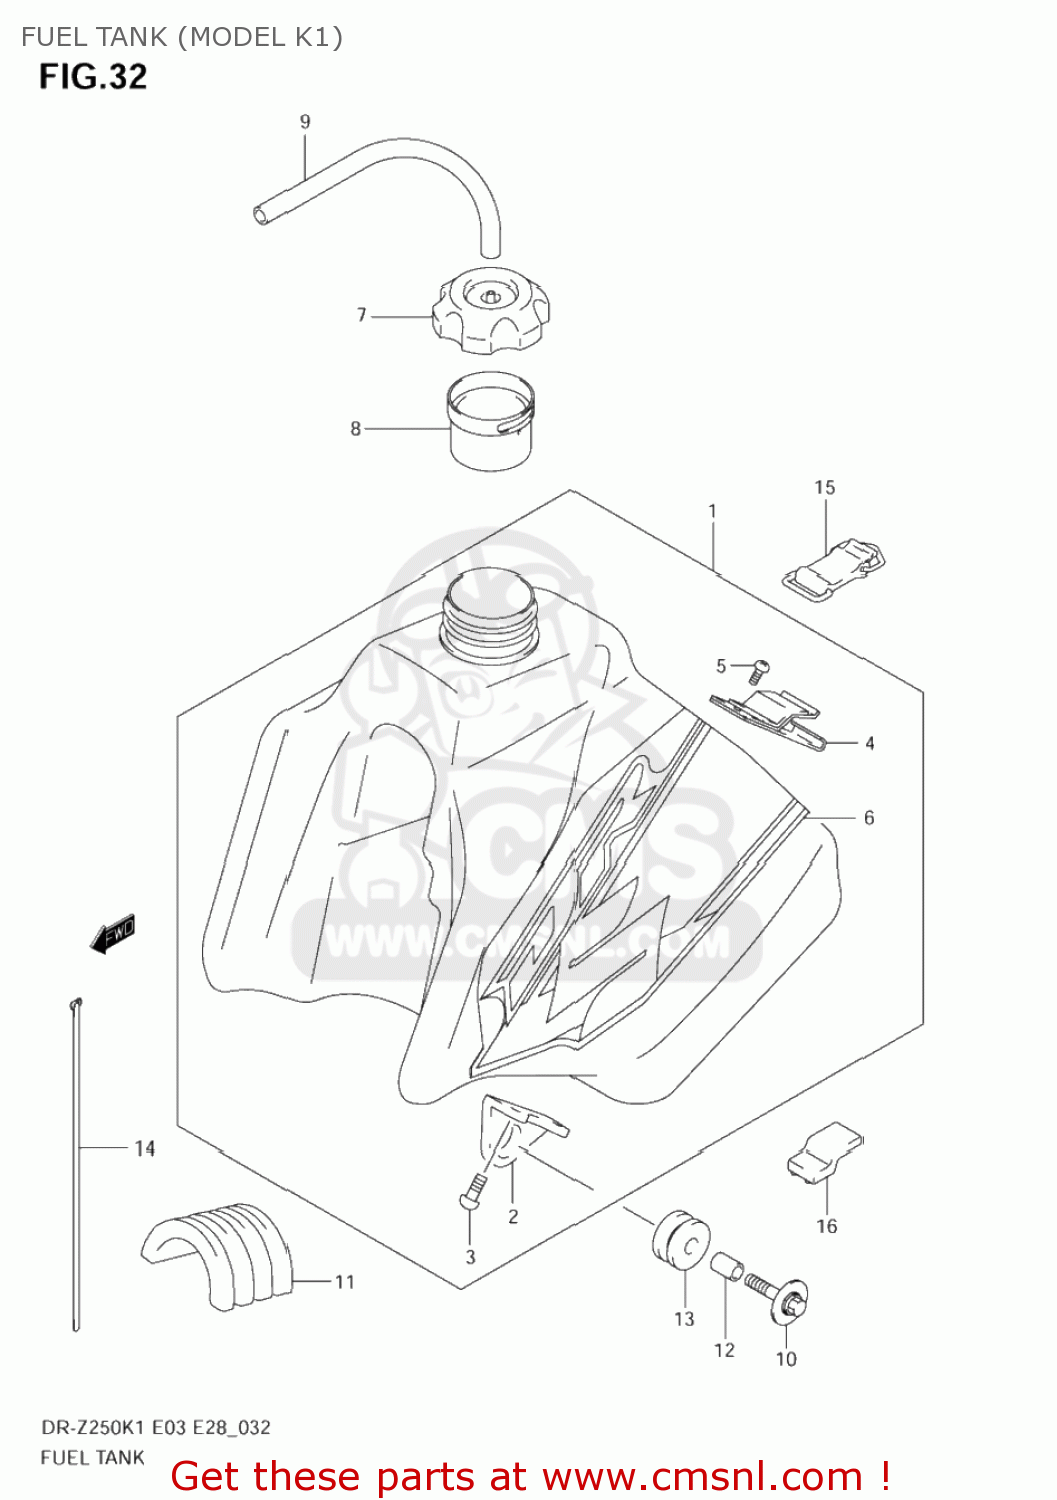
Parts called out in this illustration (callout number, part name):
1	TANK ASSY FUEL(YELLOW)
2	BRACKET,FUEL TANK FR
3	SCREW
4	BRACKET,FUEL TANK RR
5	SCREW
6	TAPE SET,FUEL TANK
7	CAP ASSY,FUEL TANK FILLER
8	TUBE,FILLER INLET
9	HOSE(5X8.2X600)
10	BOLT(6X30)
11	CUSHION,FUEL TANK
12	SPACER(6.5X9X13.5)
13	CUSHION,MUFFLER
14	CLAMP(L:300)
15	BAND,FUEL TANK RR
16	CUSHION,FUEL TANK
